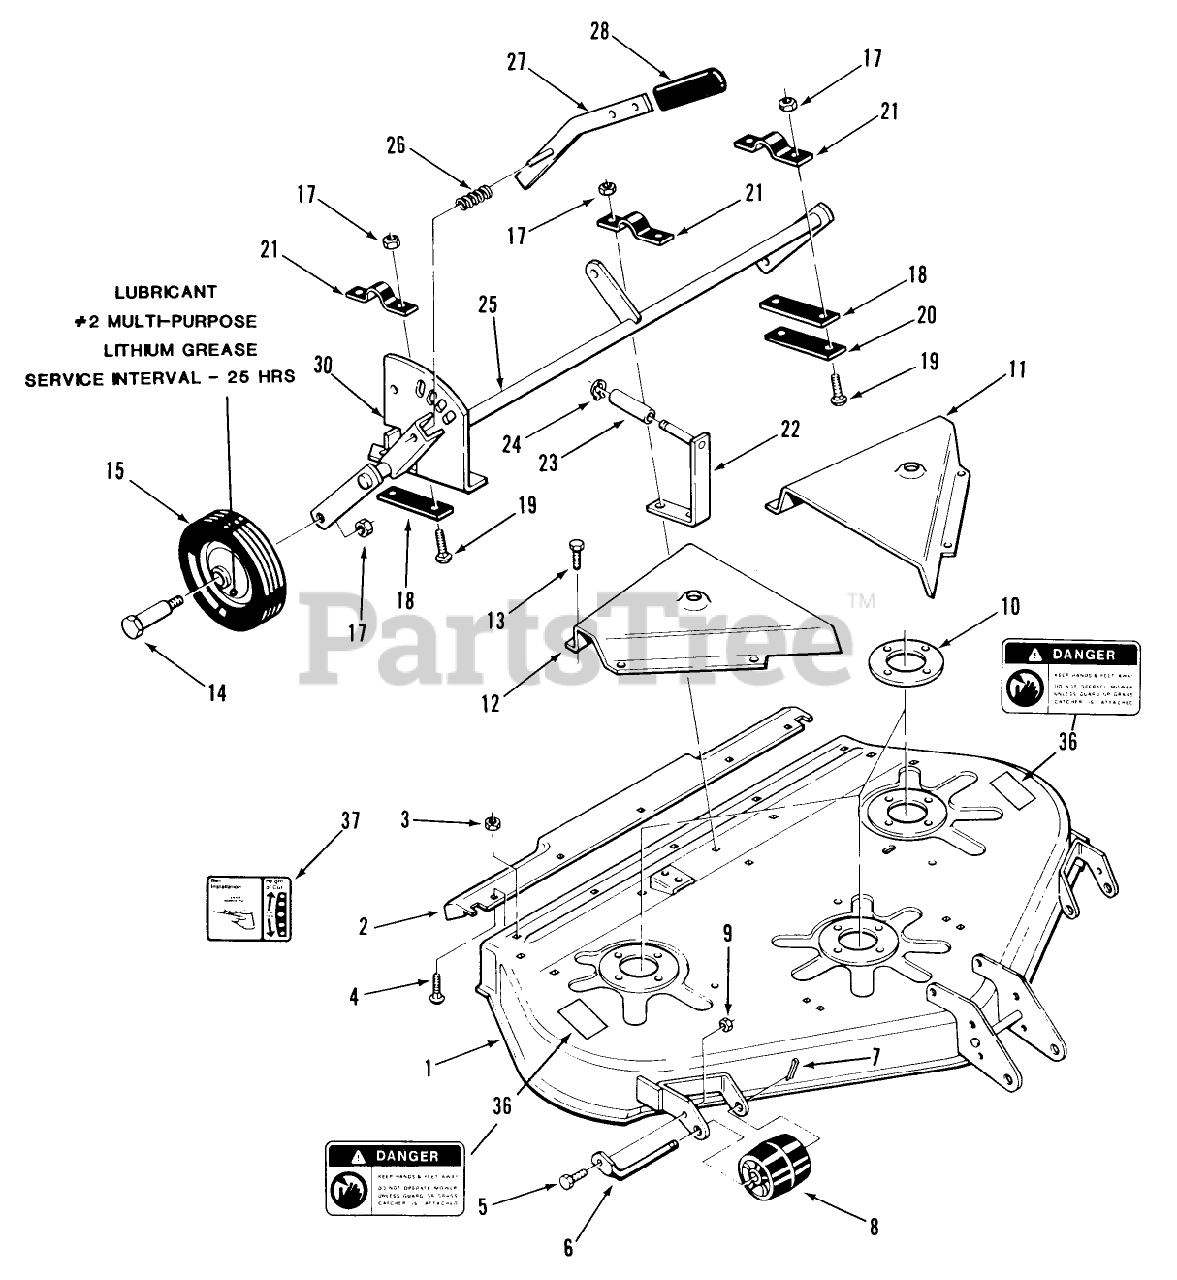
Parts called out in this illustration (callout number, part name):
1	ASSY 42" MOWER RE R
2	EXTENSION R
3	Nut
4	Bolt
5	H H C S
6	ROLLER-SHAFT
8	Roller
9	Nut
10	PLATE-SPINDLE
11	Belt Cover LH
12	Belt Cover RH
13	Bolt
14	BOLT-SHOULDER
15	WHEEL
17	Nut
18	STRAP 1/16 B
19	Bolt
20	Bar
22	Bracket Guide
23	SPACER
24	Snap Ring
25	Gage Wheel Support
26	SPRING-COMPRESSION
27	Lever
30	QUADRANT R
36	Danger Decal
37	DECAL-HEIGHT BELT
